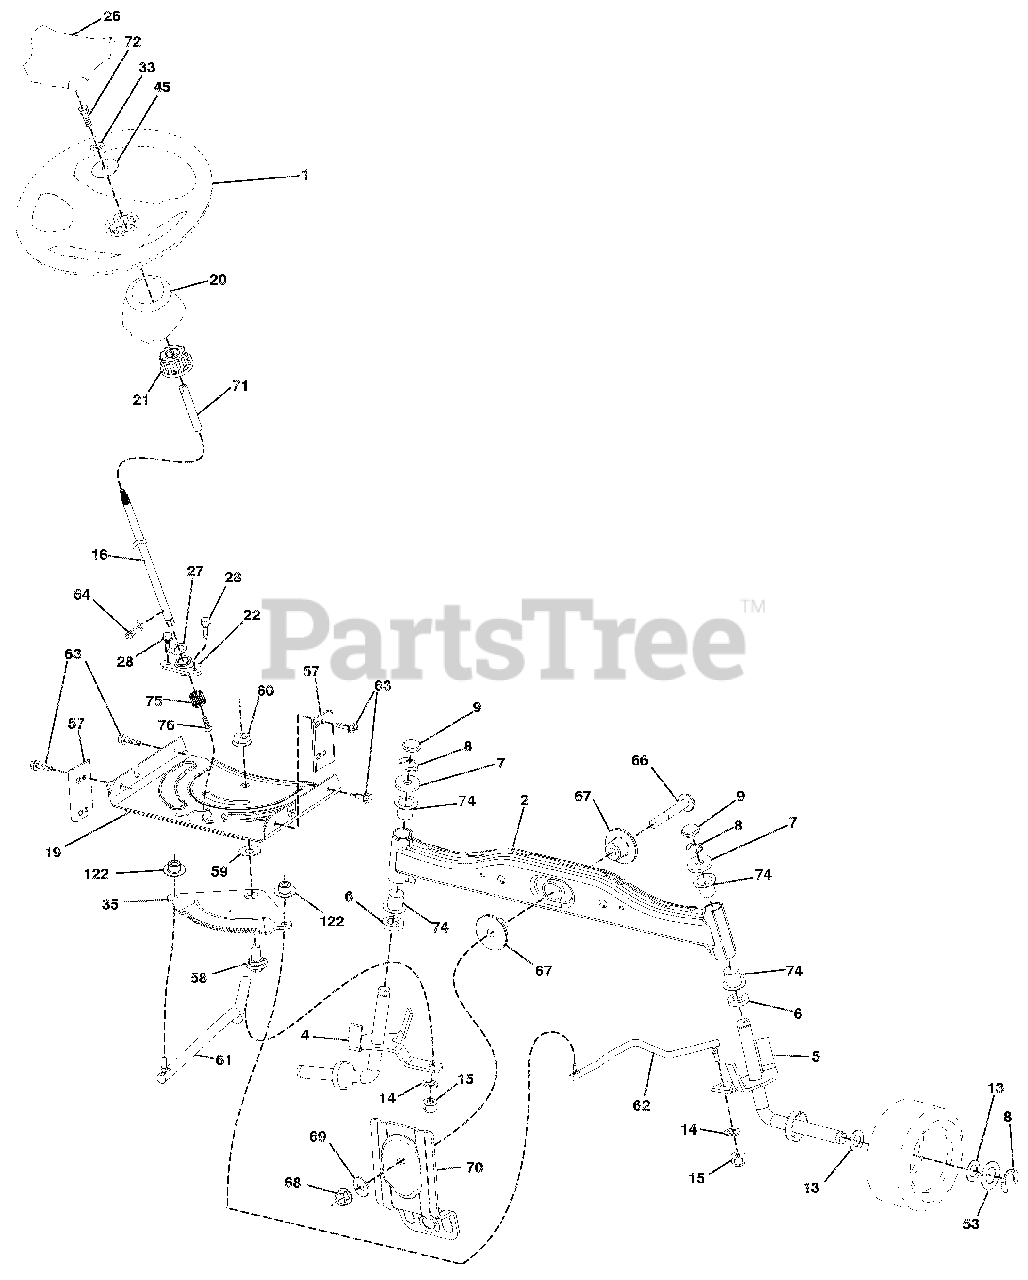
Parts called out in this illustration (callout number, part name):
1	WHEEL.STEERING.HARD RIM.BLACK
2	AXLE ASM.WELDED
4	SPINDLE.WELDED.LH.15"TEX
5	SPINDLE.WELDED.RH.15"TEX
6	WAHSER THRUST .75 X 1.230
7	WASHER.25/32 X 1-5/8 X 16GA.
8	RING.KLIP.#T5304-75
9	CAP.SPINDLE.FR.TOP.BLK.
13	WASHER.25/32 X 1 1/4 X 16 GA.
14	Washer, Lock 3/8
15	NUT.CROWNLOCK.3/8-24
16	STEERING SHAFT
19	PLATE.STEER.DDL.NLT/NGT
20	BOOT.STEERING
21	ADAPTER.WHEEL.STRG..760
22	STEER.SUPT. LOWER
26	CAP WHEEL STEERING HRS/SRS BLK
27	Washer 21/32 x 1 x 16 Ga.
28	SCREW.HEXWSH THDR3/8-16X3/4.BL
33	Washer, Lock 5/16
35	GEAR SECTOR.PLATE.DDL.NLT/NGT
45	WASHER.11/32ID X2 3/8OD X 12GA
53	WASHER.HARDEN..793 X 1.637X060
57	BRACKET.UPSTOP.TEX
58	BOLT.SHOULDER.SECTOR.PIVOT.CFM
59	WASHER.THRUST.SECTOR.STEER.NLT
60	NUT.FLANGE LOCK.5/8-11
61	DRAGLINK.LH.BALLSTUD.DDL.
62	DRAGLINK.RH.BALLSTUD.DDL
63	SCREW.5/16-18X3/4.SMGML.TAP/BL
64	RETAINER.CLIP.SPRING.STEERING
66	BOLT.HEX.FGHD.7/16-14 X 3.SERR
67	BUSHING.PM.FRONT AXLE
68	NUT.LOCK.FLANGE.7/16-14.GR5
69	WASHER.1.5 X .505 X .118
70	BRACKET.DECK.SUSPENSION.FRONT
71	Extension Steering
72	Bolt 5/16-18 x 14 w/Patch
74	BEARING COL STRNG BLK
75	PINION
122	CAP GEAR SECTOR
